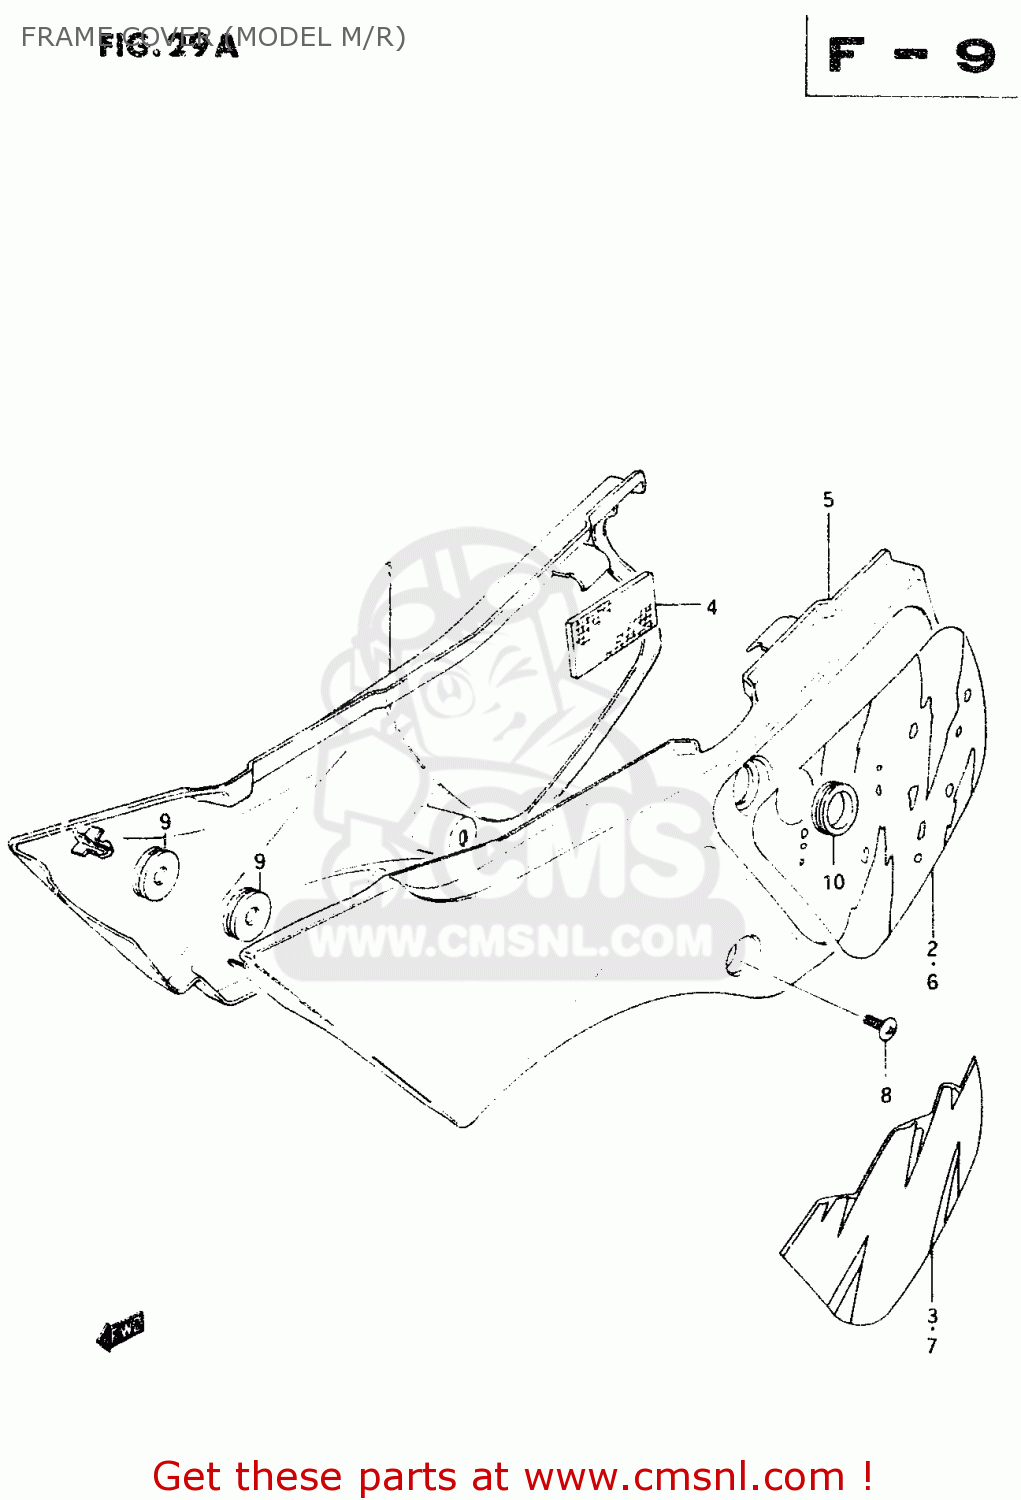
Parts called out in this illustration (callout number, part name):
1	COVER,FRAME RH
2	TAPE, FRAME COVER RH
3	TAPE,FRAME COVER,R
4	SHIELD, HEAT RH
5	COVER,FRAME LH
6	TAPE, FRAME COVER LH
7	TAPE,FRAME COVER
8	SCREW(6X12)
9	CUSHION
10	GROMMET,SEAT LOCK HOLE
